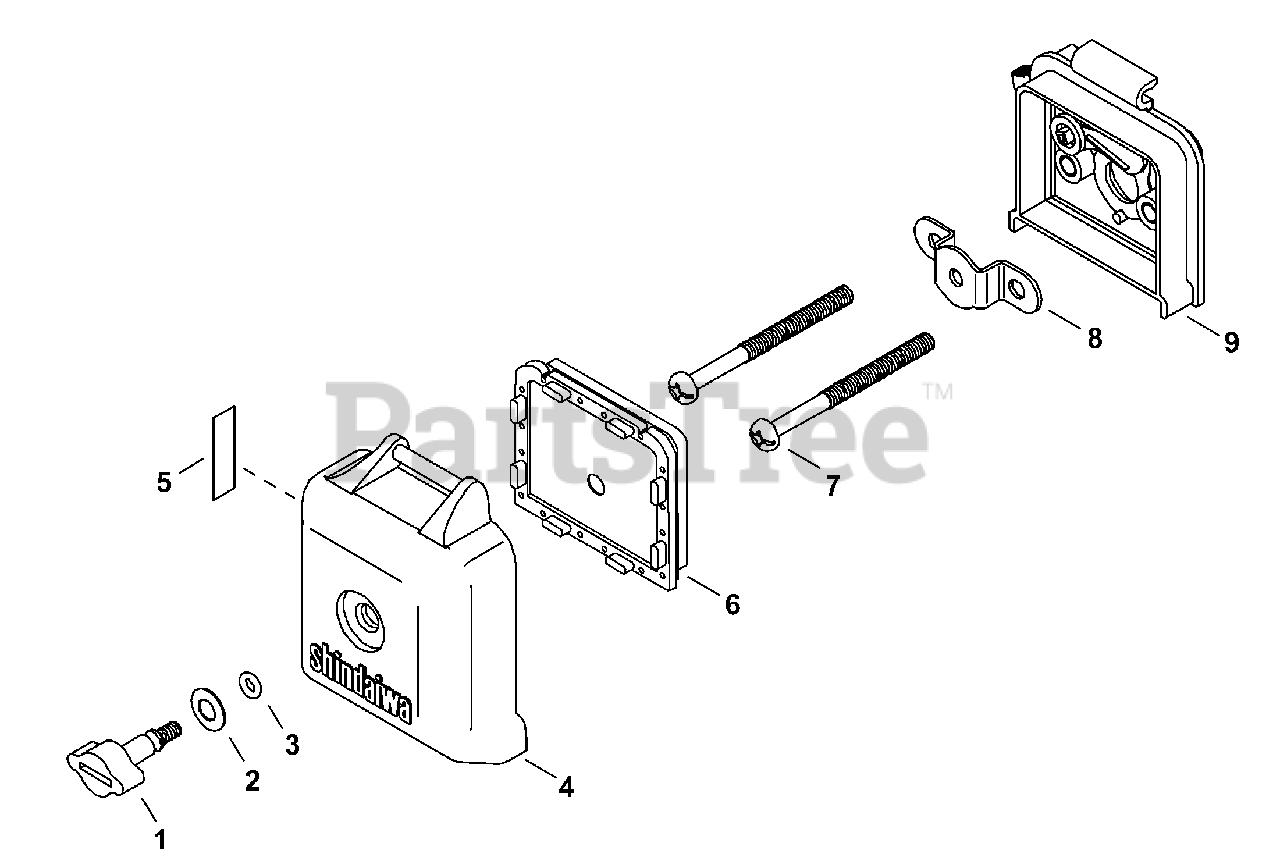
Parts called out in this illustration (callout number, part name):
1	THUMBSCREW
2	WASHER, CONE M6
4	COVER, AIR FILTER
5	LABEL, CHOKE
6	FILTER, AIR
7	SCREW M5×60
8	BRACKET
9	CASE, AIR FILTER
